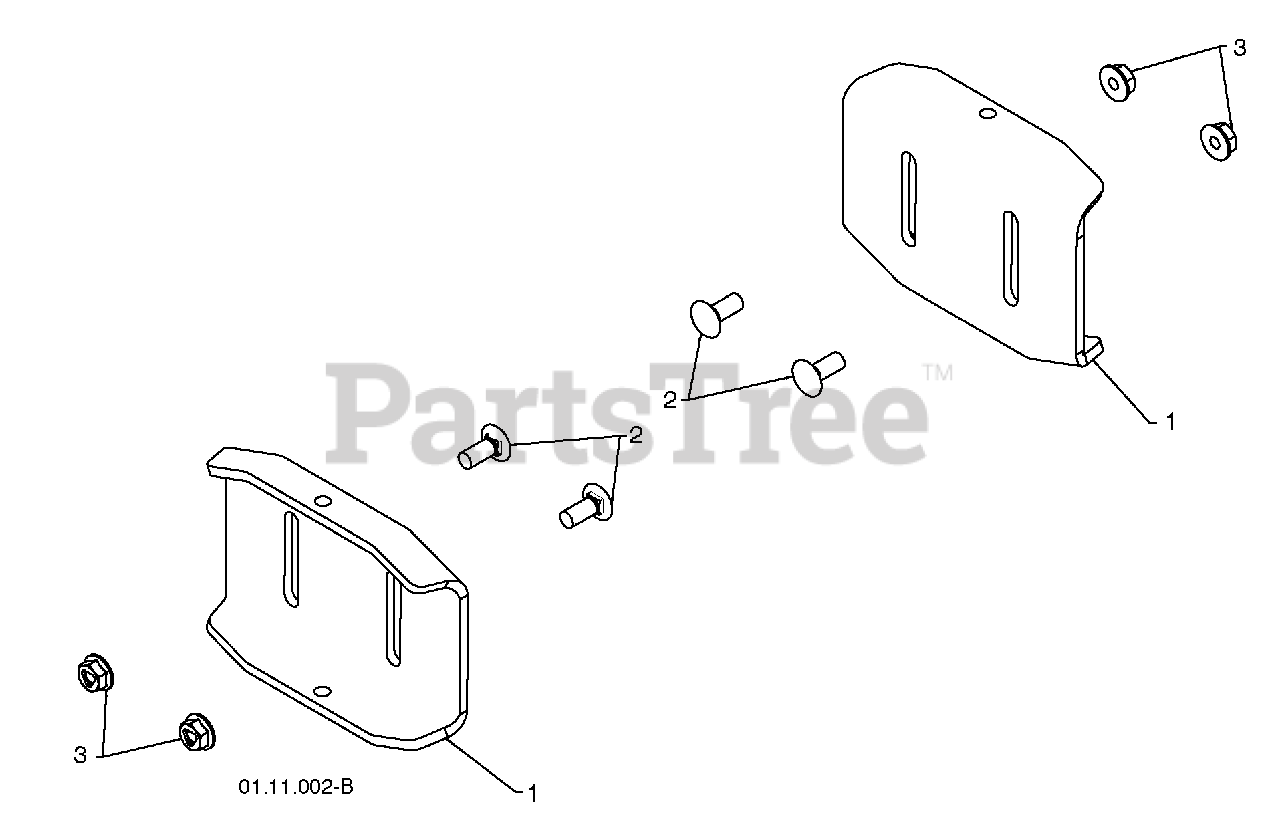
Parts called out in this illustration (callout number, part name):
1	SKID PLATE
2	CARRIAGE BOLT 5/16-18 X .750
3	NUT 5/16-18
